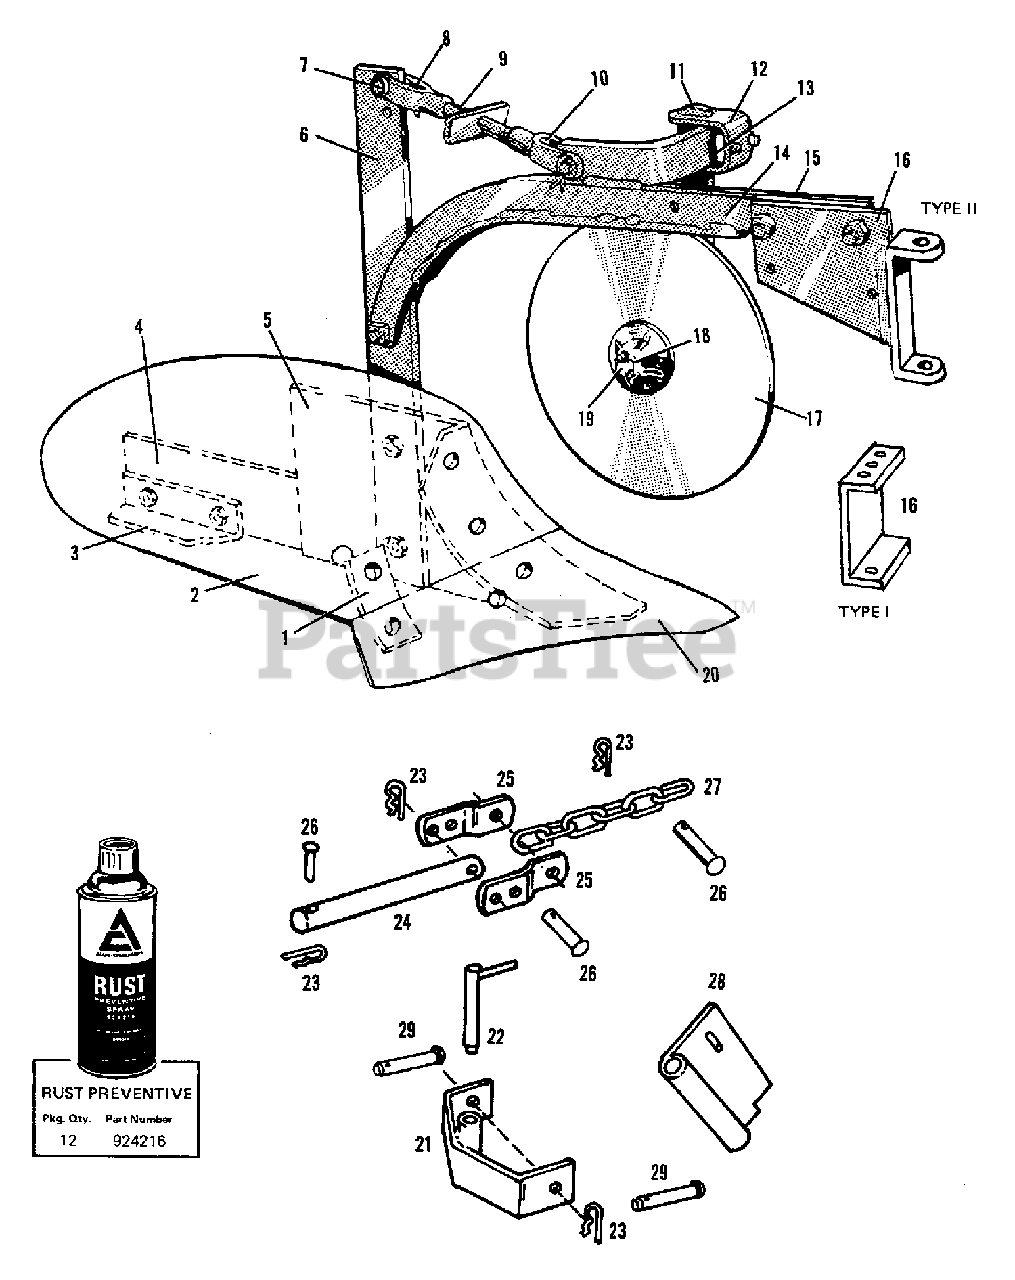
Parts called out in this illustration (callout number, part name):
1	BRACE, Moldboard
1	BOLT, Plow, 7/16NC x 1-1/4
1	NUT, Square, 7/16NC
2	MOLDBOARD
3	ANGLE, Slip Heel
3	BOLT, Plow, 7/16NC x 1-1/4
3	NUT, Square, 7/16NC
5	BOLT, Plow, 7/16NC x 1-1/4
5	NUT, Square, 7/16NC
5	BOLT, Plow, 1/2NC x 1-1/2 (For Type II Hitch)
5	NUT, Square (For Type II Hitch)
6	BOLT, Plow, 1/2NC x 1-1/2
6	NUT, 1/2NC
6	LOCKWASHER, 1/2
7	PIN, Yoke
7	PIN, Clip, Safety
7	PIN, (For Type II)(Shown)
8	YOKE, Rod, L.H.
8	NUT, 5/8NC
9	ROD ASSEMBLY, Yoke
10	YOKE, Rod, R.H.
11	STANDARD, Coulter
12	CLAMP, Coulter Standard
12	SETSCREW, 3/8NC x 1, Square Head Cup Point
13	NUT, Special
14	BEAM ASSEMBLY, Plow
14	CASPCREW, 1/2NC x 1-3/4 (To Standard)
14	NUT, 1/2NC (To Standard)
14	CAPSCREW, 3/8NC x 2-1/4 (To End Assembly)
14	NUT, 3/8NC (To End Assembly)
14	LOCKWASHER, 3/8 (To End Assembly)
15	SPACER, Plow Beam
16	END ASSEMBLY, Plow Beam (Type I)
16	END ASSEMBLY, Plow Beam (Type II)
17	COULTER ASSEMBLY, (Includes BUSHING)
17	PIN, Cotter, 1/8 x 1
17	FITTING, Lube, 1/4 (Package of 10)
17	NUT, 5/8NC
18	WASHER, Coulter
19	SPINDLE, Wheel
20	SHARE, Plow
21	CLEVER ASSEMBLY, Hitch (Type II Plow Hitch)
22	PIN ASSEMBLY, Hitch (Type II Plow Hitch)
23	CLIP, Spring (Type II Plow Hitch)
24	PIN, Plow Lift (Type II Plow Hitch)
25	BRACKET (Type II Plow Hitch)
26	PIN, 2" (Type II Plow Hitch)
27	CHAIN (Type II Plow Hitch)
27	CAPSCREW, 3/8NC x 1-1/2 (Type II Plow Hitch)
27	WASHER, 3/8 (Type II Plow Hitch)
27	LOCKWASHER, 3/8 (Type II Plow Hitch)
27	NUT, 3/8NC (Type II Plow Hitch)
28	SUPPORT ASSEMBLY (Type II Plow Hitch)
29	PIN, 1-3/4 (Type II Plow Hitch)
